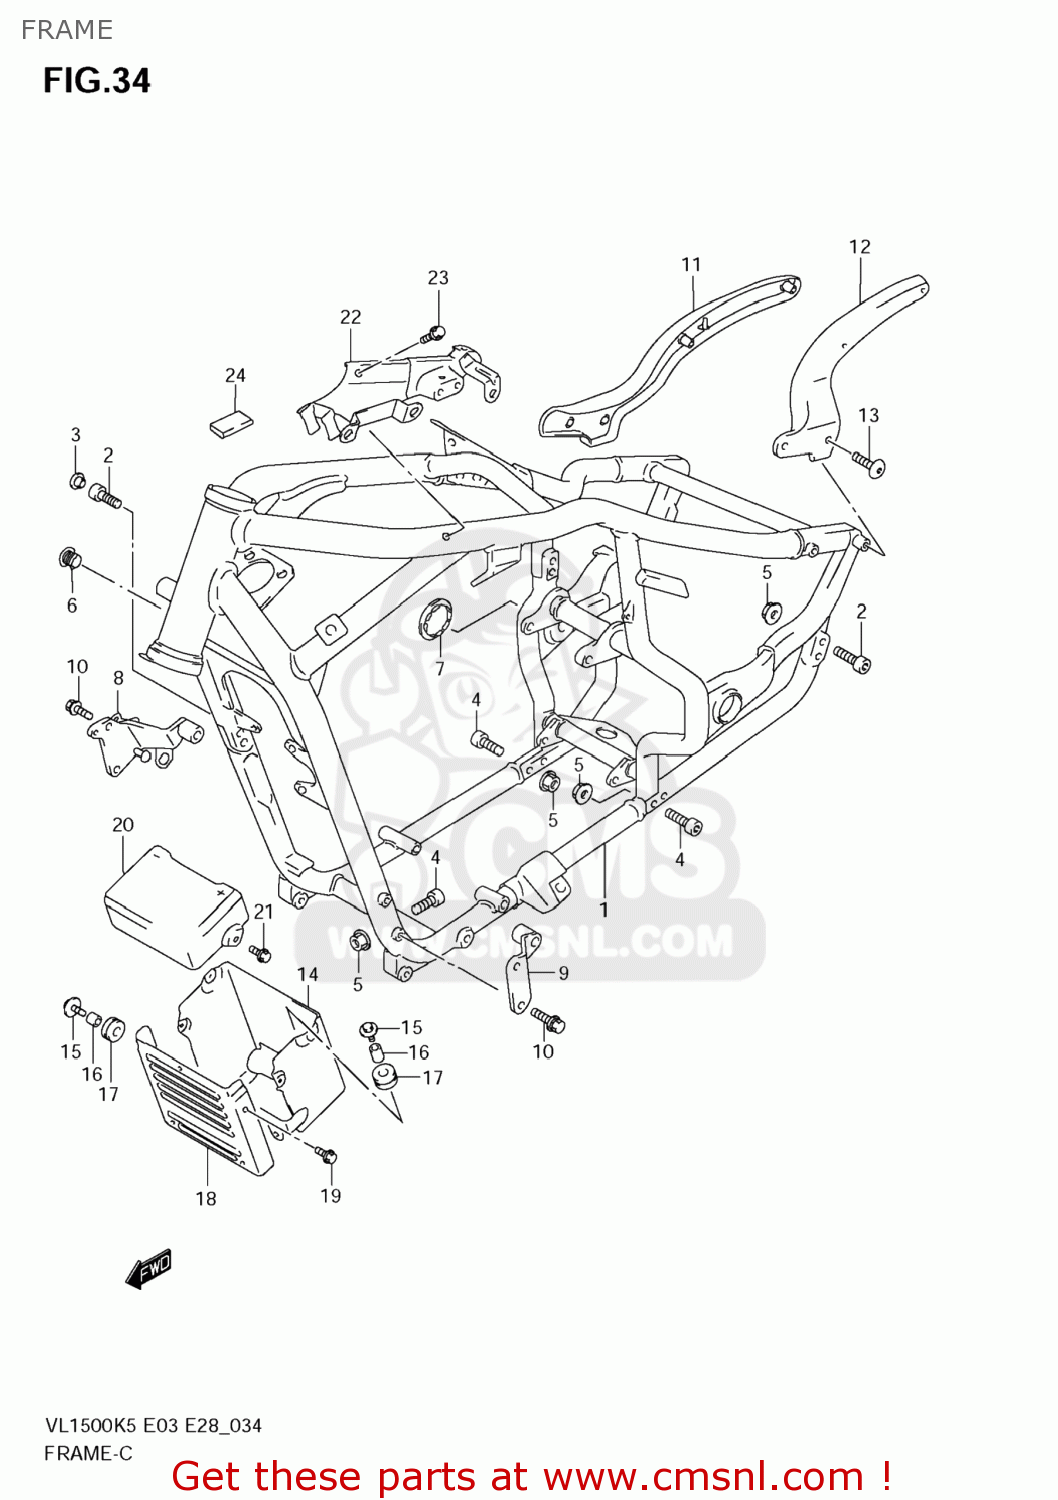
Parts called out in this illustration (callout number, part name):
1	FRAME(BLACK)
2	BOLT
3	CAP(OD:12)
4	BOLT
5	NUT
6	CAP,FRAME U-LOCK HOLE
7	CAP,FRAME PIVOT,R
8	PLATE,ENGINE MOUNT NO.1,R
9	PLATE,ENGINE MOUNT NO.1,L
10	BOLT
11	GRIP,FRAME HANDLE,R
12	GRIP,FRAME HANDLE,L
13	BOLT(10X25)
14	HOLDER,BATTERY
15	BOLT(6X16)
16	SPACER(6.5X9X8)
17	CUSHION
18	HOLDER,BATTERY FR
19	SCREW
20	COVER,BATTERY UPR
21	BOLT
22	HOLDER,ELECTRIC PARTS
23	BOLT
24	CUSHION
